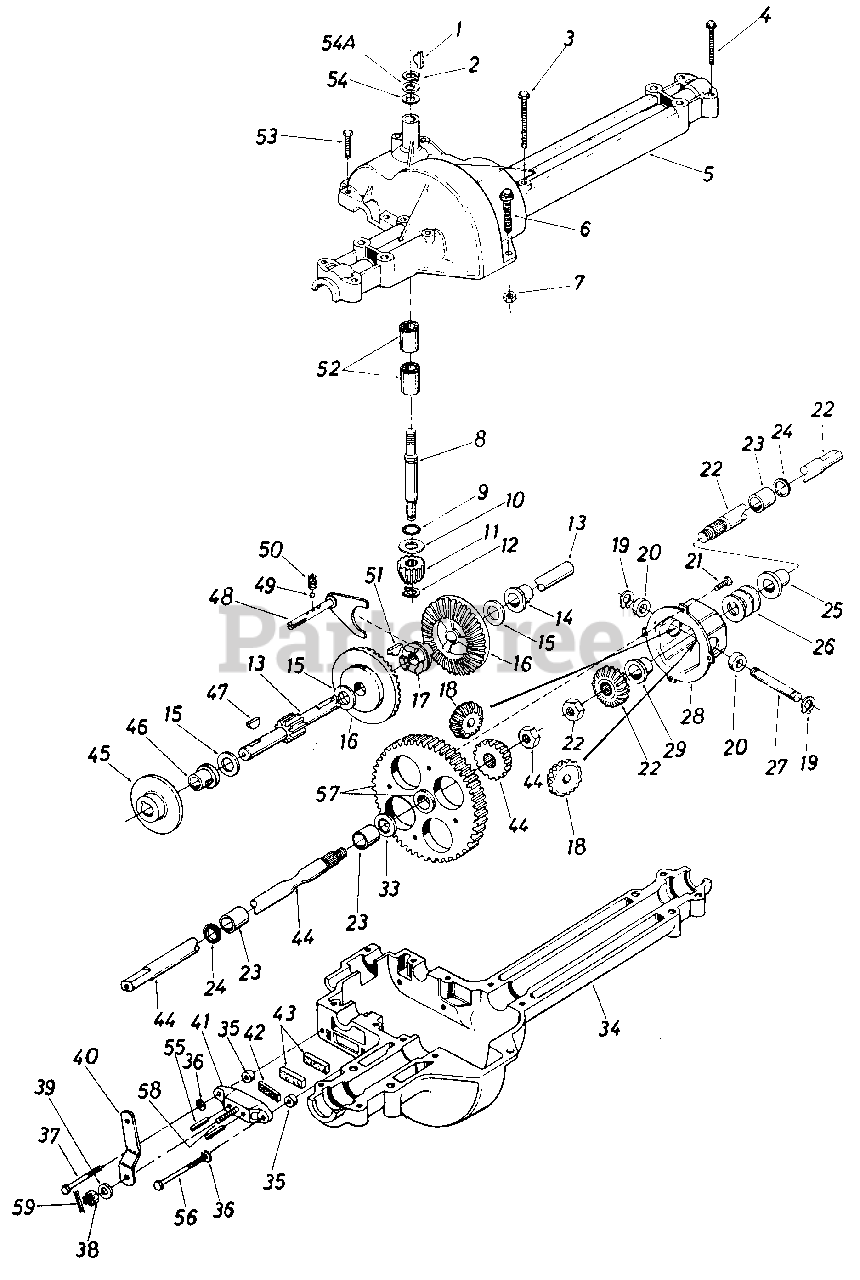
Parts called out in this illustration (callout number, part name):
1	#4 Hi-Pro Key 3/32 x 518" Dia.
2	Snap Ring .625" Shaft
3	Hex Bolt 1/4-20 x 1.75" Lg.
4	Hex Bolt 5/16-18 x 2.5"
5	Upper Housing
6	Hex Fl-Bolt 1/4-20 x .88" Lg.
7	Hex Nut 1/4-20 Thd.
8	Input Shaft
9	Square Seal 518" I.D.
10	Thrust Washer 518" I.D. x 1.25" O.D.
11	Pinion Input 14T
12	Retaining Ring 7116" Ext.
13	Drive Shaft
14	Flange Brg. 518" I.D. x 3/4"
15	Fl-Wash.
16	Bevel Gear 42T
17	Clutch Collar
18	Miter Gear 15T
19	Snap Ring
20	Thrust Bearing 1/2" I.D. x 1.0" O.D.
21	Pan Head Scr. 1/4-20 x .501' Lg. w/Patch
22	Axle R.H. Ass'y. Kit
23	Sleeve Bearing 3/4" I.D. x 1.0" Lg.
24	Oil Seal 3/4" I.D.
25	Flange Bearing 3/4" I.D. x 15/16" Lg.
26	Fl-Wash. .760" I.D. x 1.49" O.D.
27	Cross Shaft
28	Differential Housing Ass'y.
33	Fl-Wash. .760" I.D. x 1.49"
34	Lower Housing
35	Spacer .53" O.D. x 3/8" Lg.
36	L-Wash. l/4" I.D.
37	Hex Bolt 1/4-20 x 1.50" Lg. (Grade 5)
38	Castle Nut 5/16-24 Thd.
39	Fl-Wash. .344' I.D. x .875" O.D.
40	Actuating Arm
41	Brake Yoke
42	Puck Plate
43	Brake Puck
44	Axle L.H. Ass'y. Kit
45	Brake Disc
46	Flange Bearing 5/8" I.D. x 15/16" Lg.
47	Woodruff Key 3/16 x 5/8 HT
48	Shift Fork Ass'y.
49	Ball Detent .250" Dia.
50	Spring Detent
51	#9 Hi-Pro Key 3/16" x 3/4" Dia. HT
52	Needle Brg. 5/8" I.D. x 1/2" Lg.
53	Hex Bolt 1/4-20 x 1.00" Lg.
54	Fl-Wash. 5/8" I.D. x .030
54A	Fl-Wash. 5/8" I.D. x .040
55	Actuating Pin 5/16" Dia.
56	Hex Bolt 1/4-20 x 2.501' Lg. (Grade 5)
57	Differential Gear 72T Ass'y. w/Bearing
58	Sq. Hd. Bolt 5/16-24 Thd.
59	Cotter Pin 3/32" Dia. x .50" Lg.
